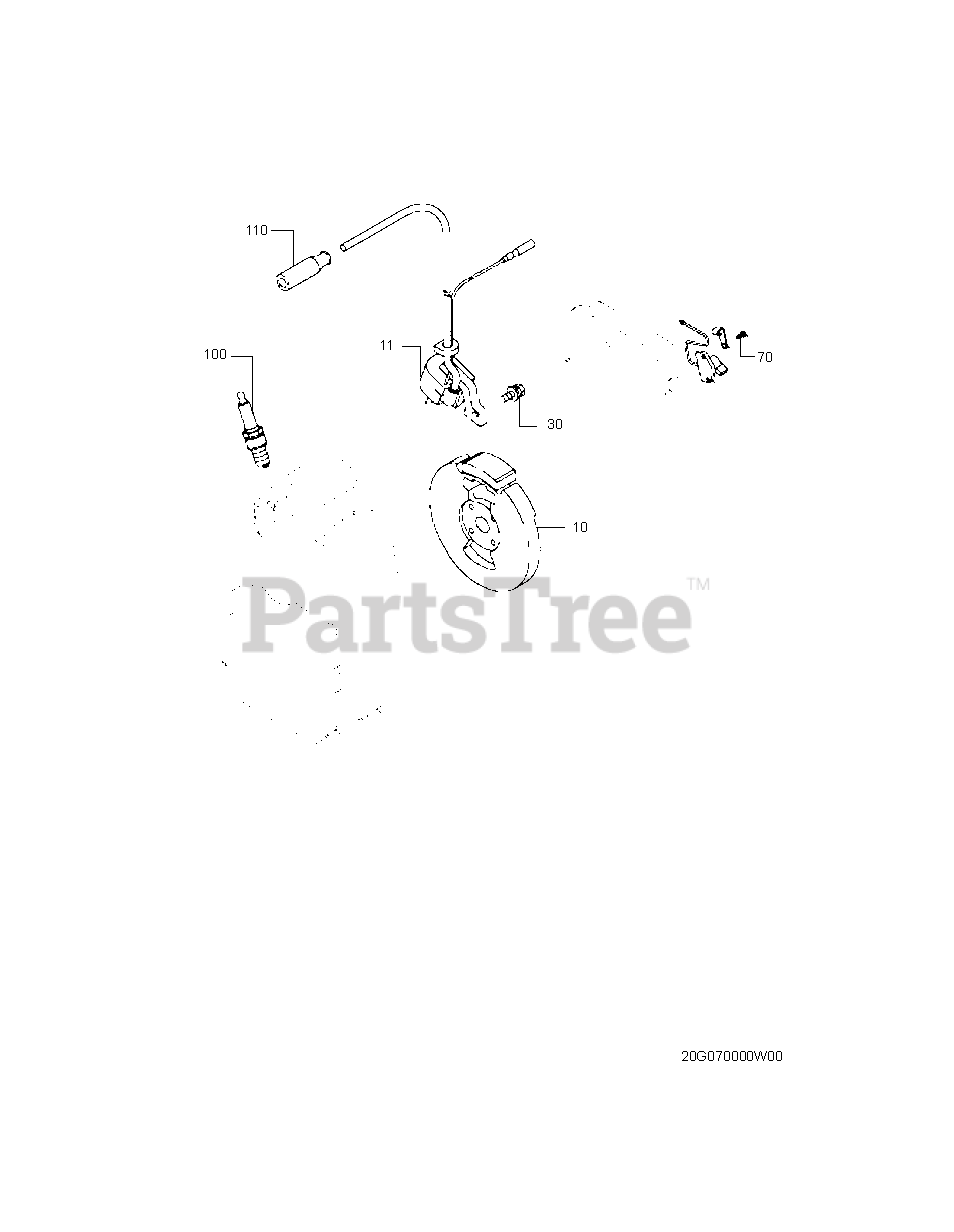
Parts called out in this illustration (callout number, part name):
11	IGNITION COIL CP
30	BOLT & WASHER AY
70	SCREW AND WASHER AY
110	SPARK PLUG CAP
